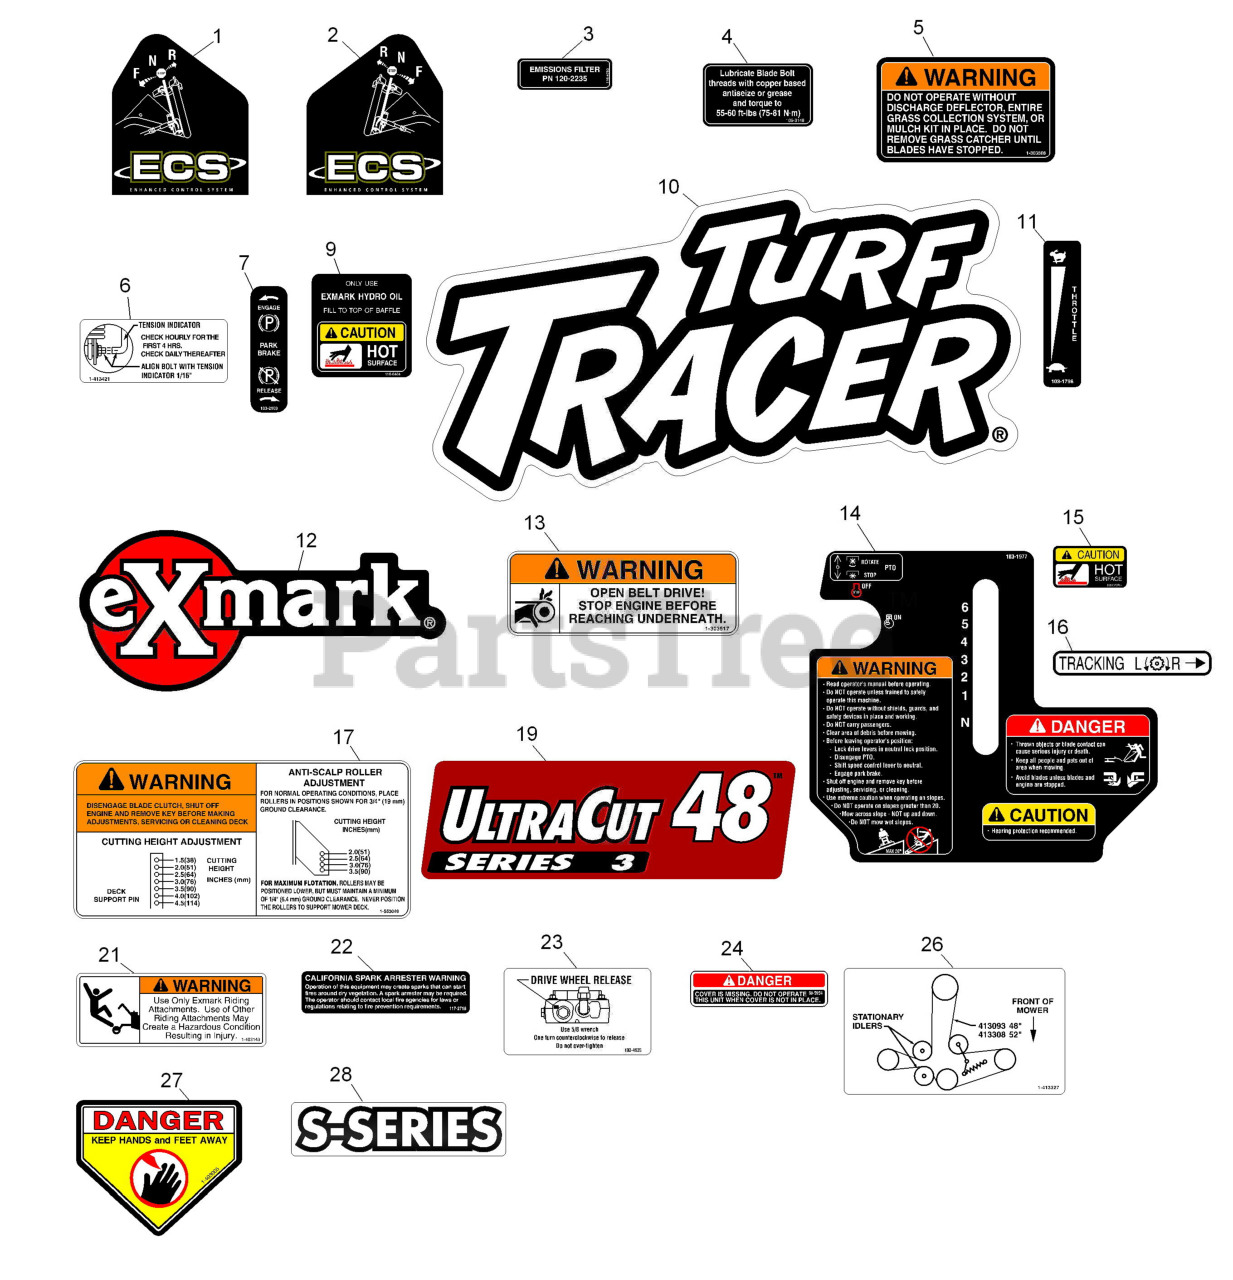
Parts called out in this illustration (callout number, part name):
1	DECAL,LH ECS INSTRUCTION
2	DECAL,RH ECS INSTRUCTION
3	DECAL-FILTER, EMISSIONS
4	DECAL,BOLT TORQUE
5	DECAL-WARNING, DISCHARGE
6	DECAL,INDICATOR
7	DECAL-BRAKE, PARK
9	DECAL-HYDRAULIC TANK
10	DECAL,TTH MODEL
11	DECAL,THROTTLE ONLY
12	DECAL,EXMARK LOGO
13	DECAL,BELT DRIVE
14	DECAL,ECS CONSOLE
15	DECAL-CAUTION
16	DECAL,TRACKING ADJUST
17	DECAL,ANTI SCALP
19	DECAL-ULTRACUT 48 SERIES
21	DECAL,SULKY WARNING
22	DECAL-ARRESTER, SPARK
23	DECAL,DRIVE RELEASE
24	DECAL-COVER, MISSING
26	DECAL,BELT ROUTING
27	DECAL-DANGER
28	DECAL-S-SERIES
